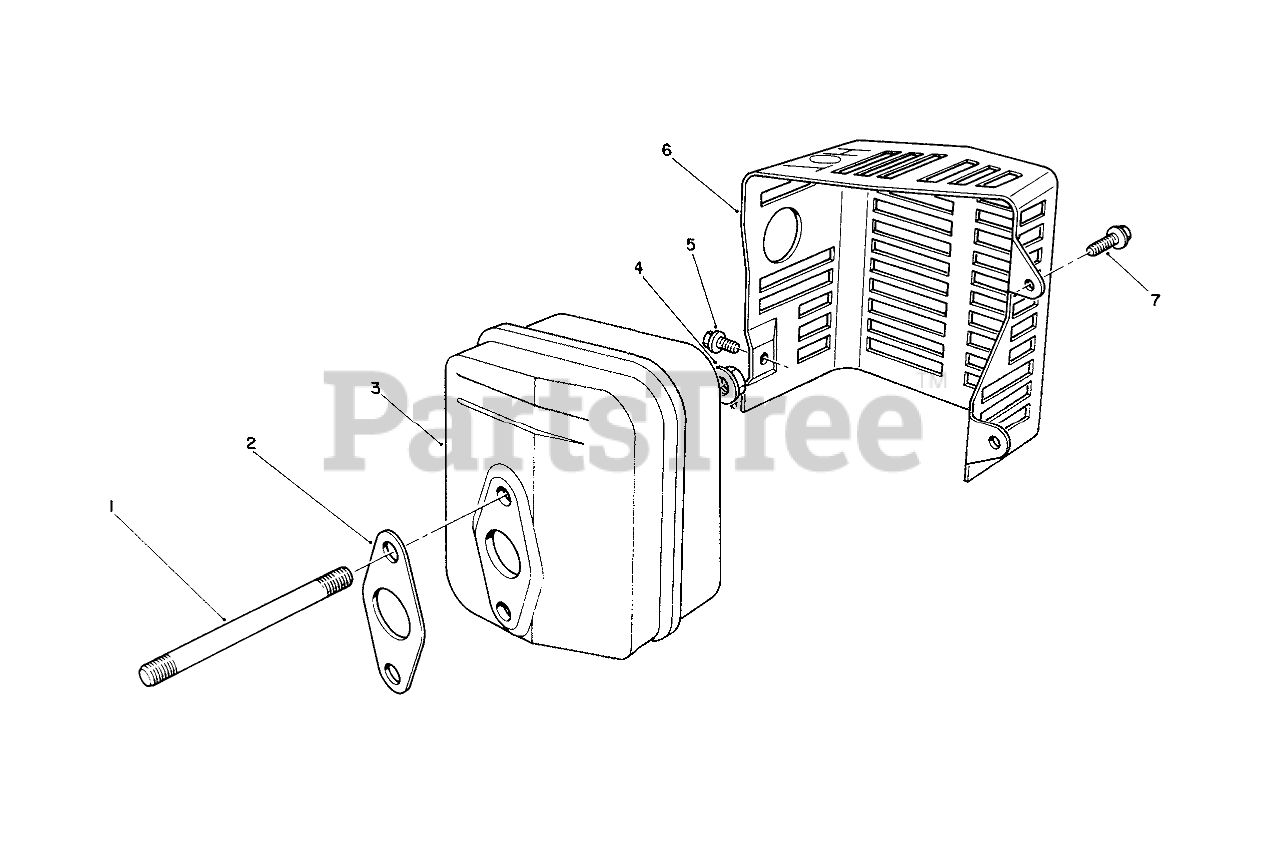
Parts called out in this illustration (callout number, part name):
2	GASKET
3	MUFFLER
5	SCREW
6	COVER
